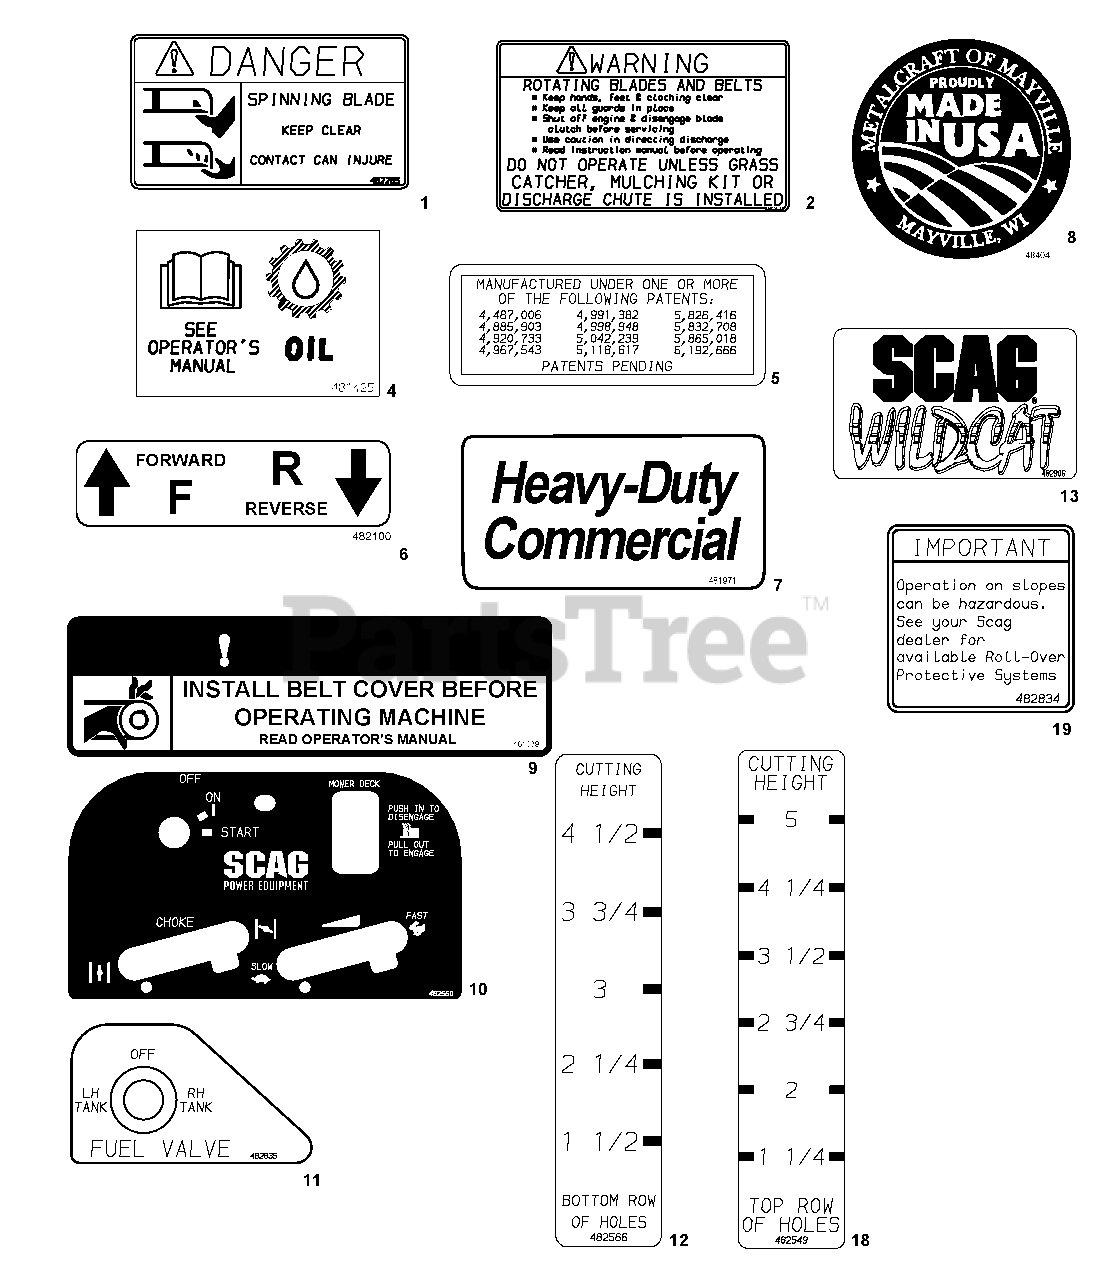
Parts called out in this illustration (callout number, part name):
1	Decal, Danger-Spining Blades
2	Decal, Warning-Rotating Blades
4	Decal, Oil
5	Decal, Patents
6	Decal, Traction Control
7	Decal, Heavy Duty Commercial
8	Decal, Metalcraft - Made in USA
9	Decal, Belt Cover
10	Decal, Instrument Panel
11	Decal, Fuel Valve Position
12	Decal, Cutting Height Bottom Row of Holes
13	Decal, Wildcat
18	Decal, Cutting Height Top Row of Holes
19	Decal, ROPS
